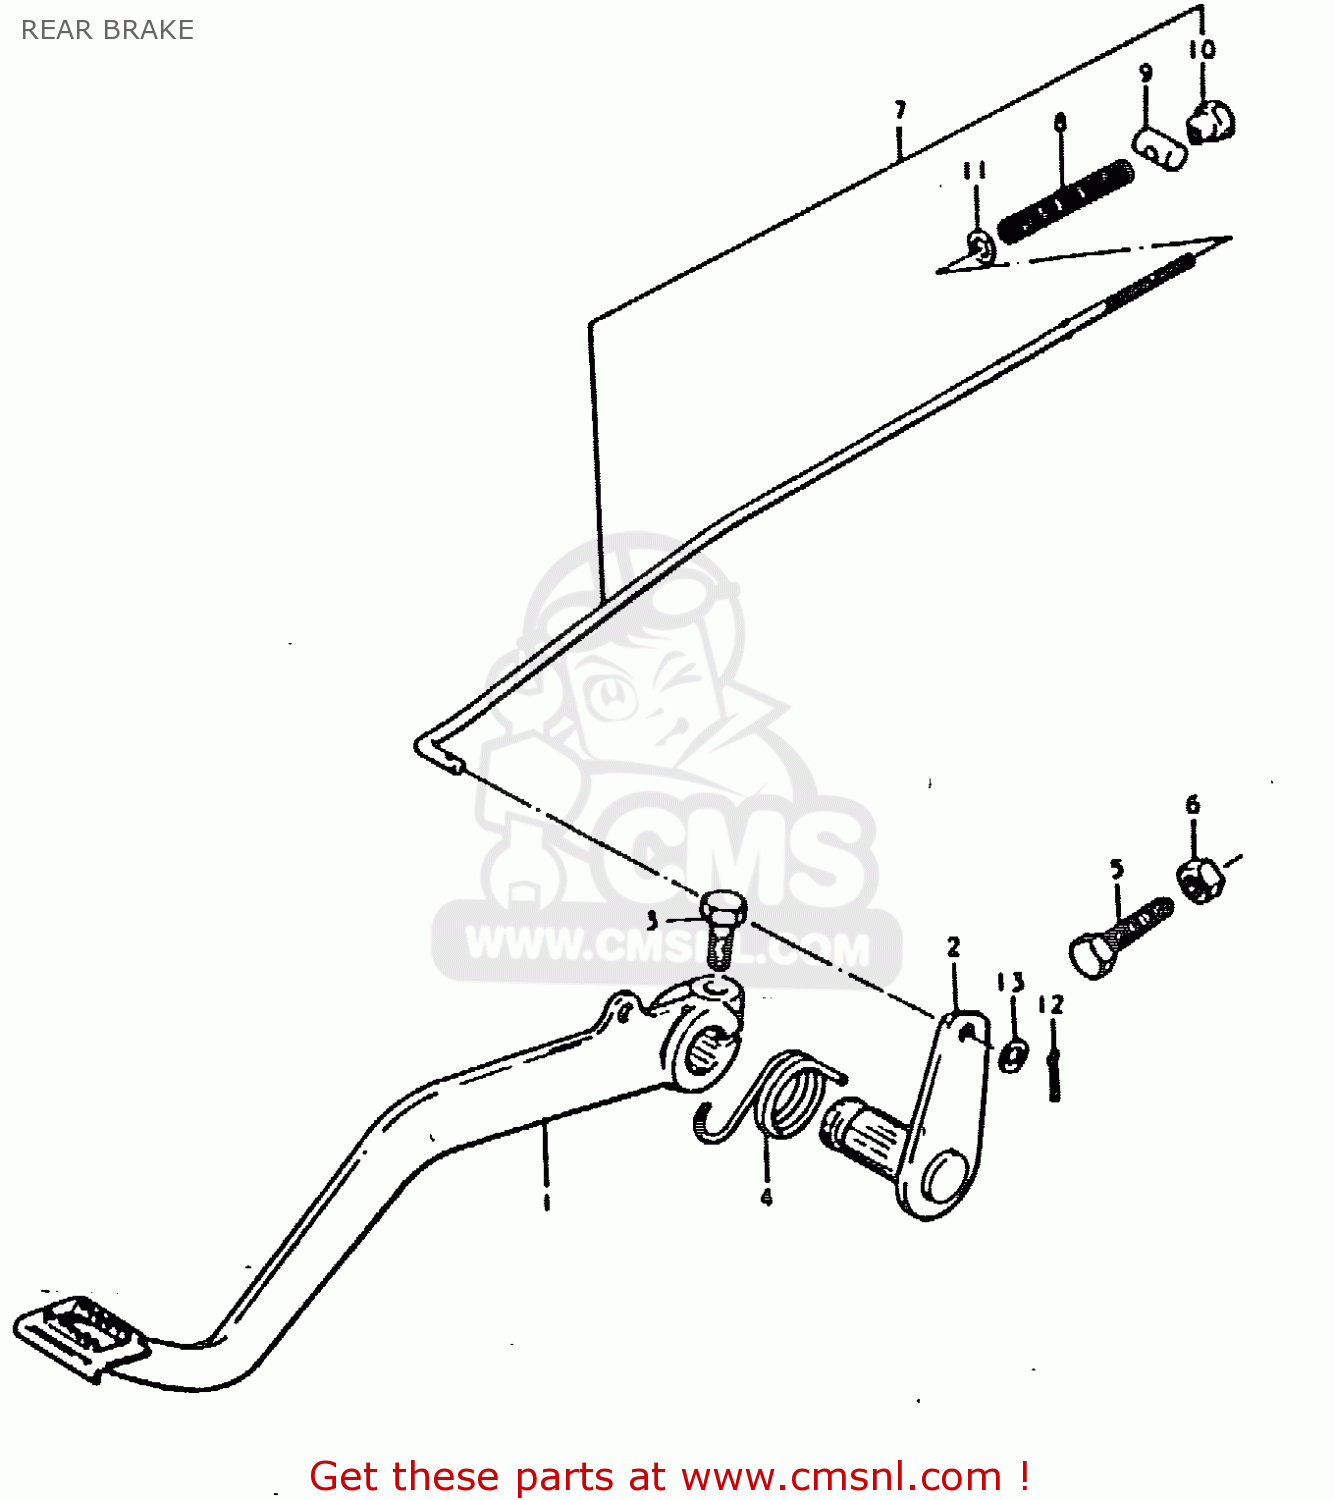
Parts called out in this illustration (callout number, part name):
1	PEDAL,BRAKE
2	ARM,BRAKE PEDAL ROD
3	BOLT
4	SPRING
5	BOLT(6X23)
6	NUT
7	ROD, REAR BRAKE
8	SPRING
9	PIN(11X18)
10	NUT
11	WASHER
12	PIN 20X20
13	WASHER
